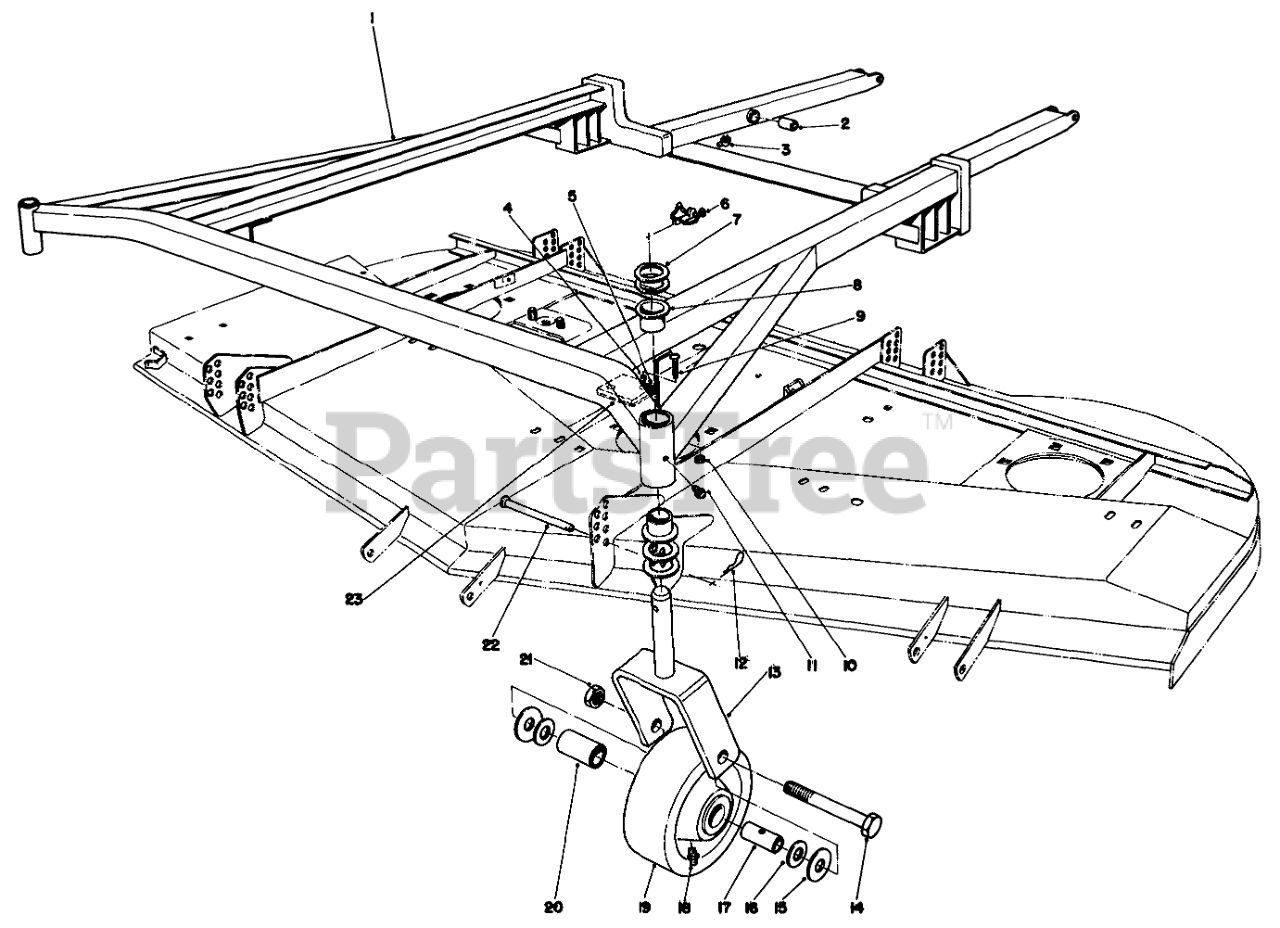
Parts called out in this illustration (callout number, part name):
1	Frame (Incl. Ref. #2, 3 & 6)
2	7/8 ID X 1.128 X 7/8 LG BSHG
3	FITTING-GREASE, 90 DEG
4	SPACER
5	CUSHION-RUBBER
6	PIN-LYNCH
7	WASHER-THRUST
8	Bushing
10	NUT-LOCK, NI
11	FITTING-GREASE
12	PIN-HAIR
13	FORK-Castor
14	SCREW-HH
15	THRUST WASHER
16	BEARING RETAINER
17	SPANNER BUSHING
18	FITTING-GREASE
19	Castor Wheel (Incl. Ref. #17-21)
20	ROLLER BEARING
21	NUT-LOCK
22	PIN-CLEVIS
23	SHIM-CUSHION
